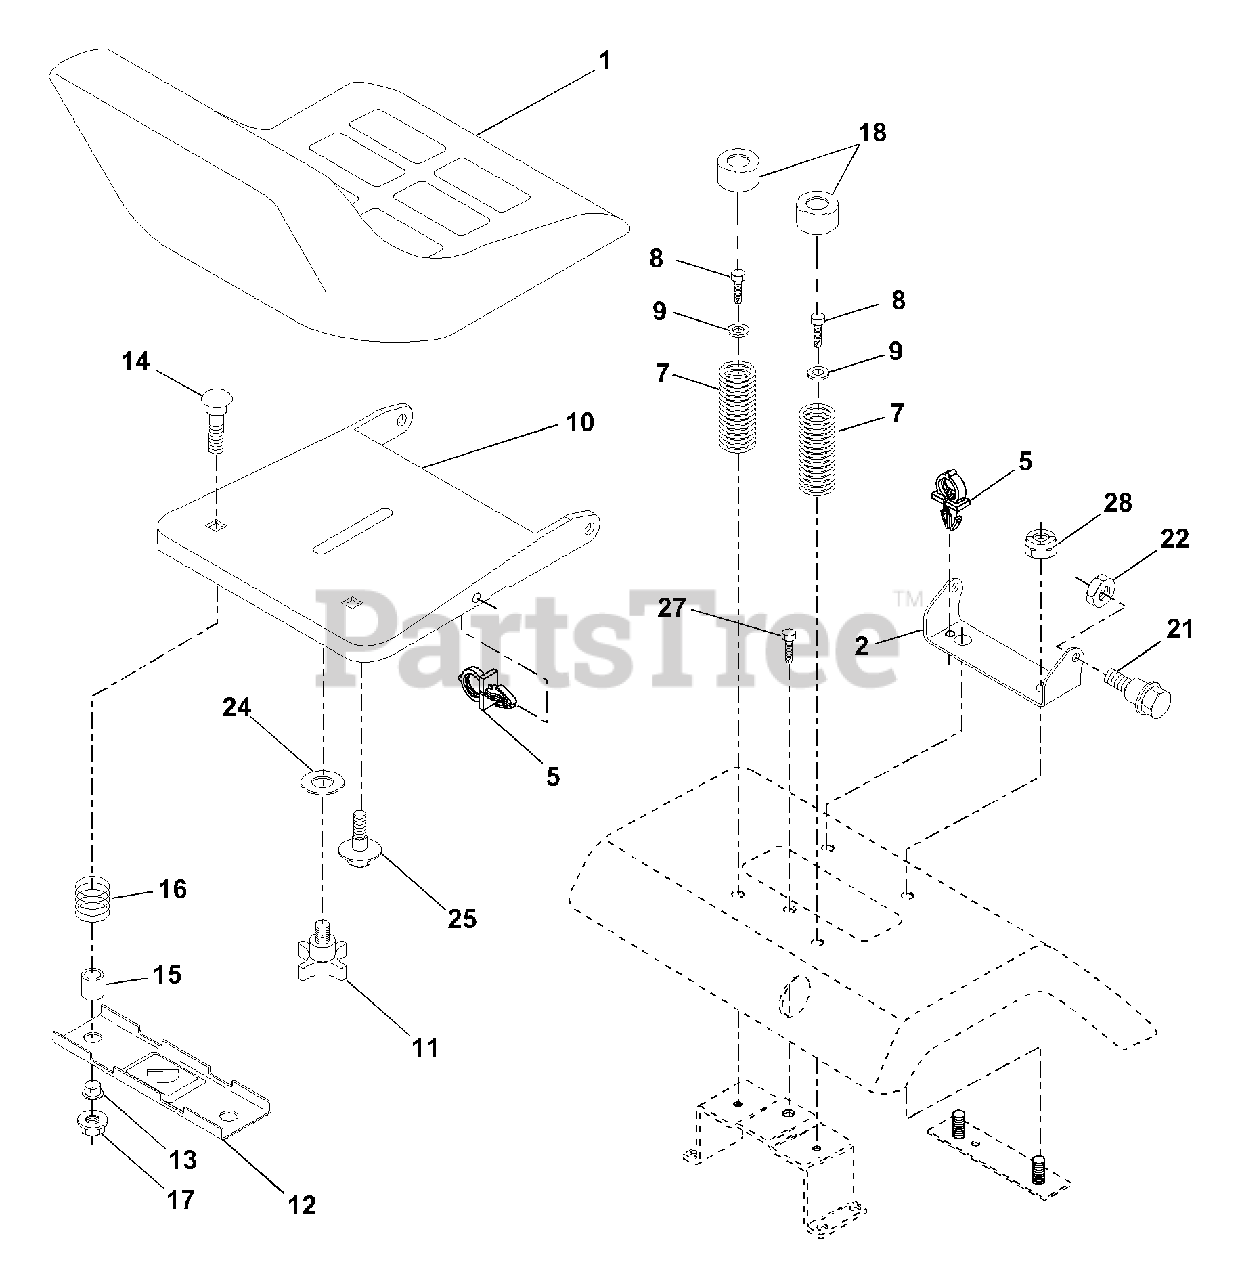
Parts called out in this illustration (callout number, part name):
1	Seat V-550 Gry/blk Std
2	Bracket Pivot Seat 8 720
5	Clip Push-in Hinged
7	Spring Seat Cprsn 2 250 Blk Zi
8	Screw Hwsh Thdrol 5/16-18 x 1/2
9	Washer 13/32 X 1 X 14 Ga
10	Pan Seat
11	Knob Seat 1/2-13unc Blk
12	Bracket Mounting Switch
13	Bushing Snap Blk Nyl 50 Id
14	Bolt Rdhd Sht Nk 1/4-20x1-3/8
15	Spacer Split 28x 88 Yel Zinc
16	Spring Cprsn 1 310 Blk Pnt
17	Nut Lock 1/4 Lge Flg Gr 5 Zinc
18	Cap Spring Seat
21	Bolt Shoulder 5/16-18 Unc Blkz
22	Nut Crown Lock 5/16-18
24	Washer 17/32 X 1-3/16 X 12 Ga
25	Bolt Shoulder 5/16-18 X 62
27	Screw Thdrol 3/8-16 x 1/2 Ty-TT
28	Nut Crownlock 3/8-16 Unc
